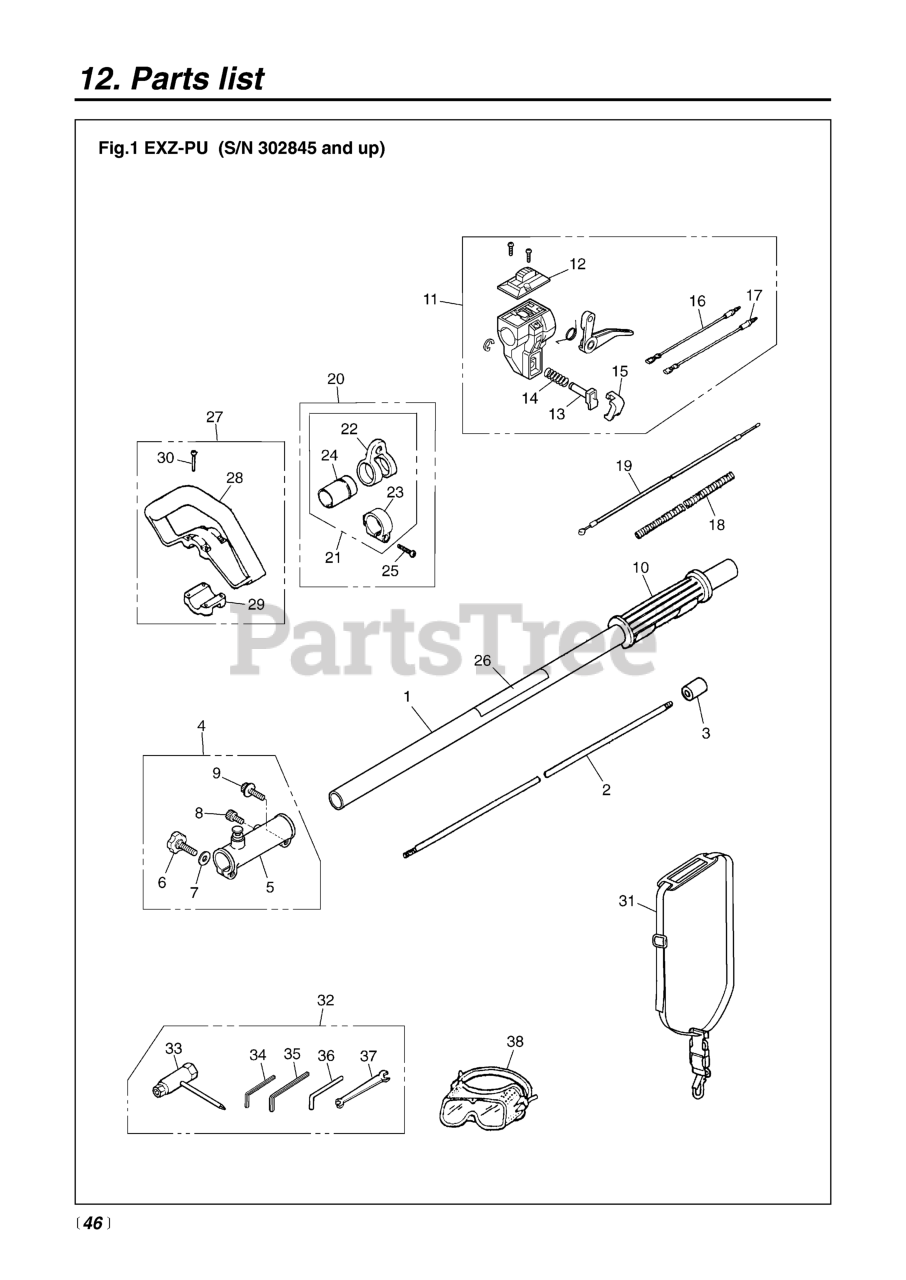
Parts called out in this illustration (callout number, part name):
1	PIPE COMPLETE
2	SHAFT
3	SPACER
4	JOINT, PIPE ASSY
5	JOINT
6	BOLT, KNOB
7	WASHER, M8 x 2.3 (RPLS -20823)
8	BOLT, M5 X 10
9	BOLT, M6 x 1.35
10	GRIP (RPLS 3577-32140 & 3220-
16	CORD (A), BLACK
17	CORD (B), RED
18	TUBE (RPLS 4900-72141)
19	CABLE (RPLS 5580-83100)
20	HANGER ASSEMBLY
21	HANGER COMPLETE
22	HANGER
23	CLAMP
24	SLEEVE
25	SCREW, M5 x 25
26	NAMEPLATE
27	HANDLE ASSEMBLY
28	HANDLE
30	SCREW, M5 x 35
31	STRAP ASSY.
33	SOCKET
34	WRENCH (TOOL)
35	WRENCH (TOOL)
36	BAR
37	SPANNER, 8 X 10 (RPLS 2540- )
38	GOGGLE
